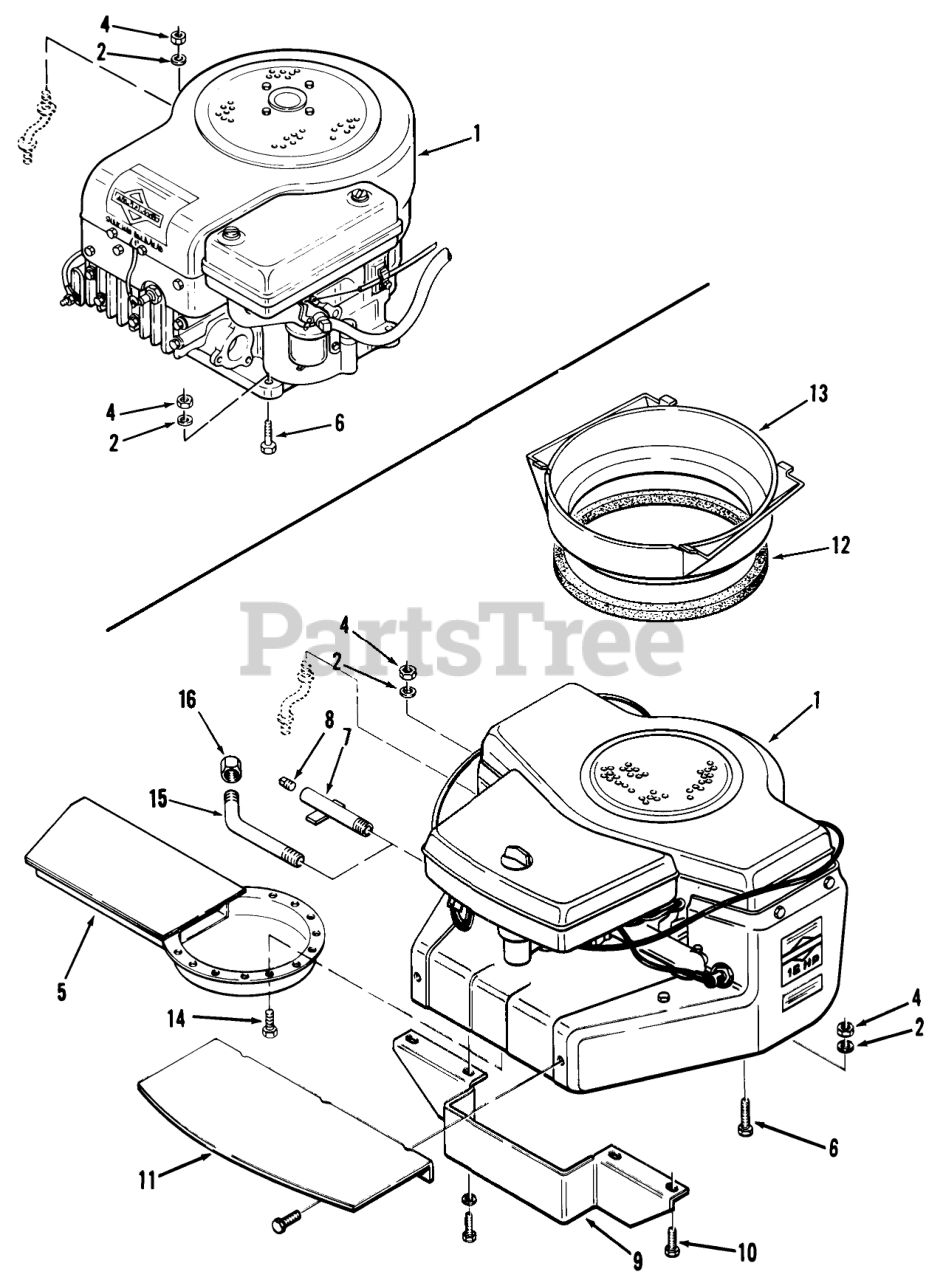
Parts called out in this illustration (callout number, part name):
1	Engine-11HP-B&S Model 252707, Type 0209-01
1	Engine-16HP-B&S Model 401707, Type 0632-01 Later Production
1	Engine-16HP-B&S Model 402707, Type 0130-03, LT-1637 Only
1	Engine-8HP-B&S Model 191707, Type 1136-02-B-85 Only
2	WASHER 5/16 SAE
4	Nut
5	Exhaust Deflector B-165 Only
6	Bolt
6	HHCS
7	Drain Pipe B-165 Only
8	Plug-Pipe 1/4-18
9	Duct-Rear 216-5 Only
10	Bolt
11	Duct-Front B-165 Only
12	Insulation-Hood B-165 Only
13	DUCT-AIR INTAKE
14	SCREW 8-32X3/8
16	Cap
